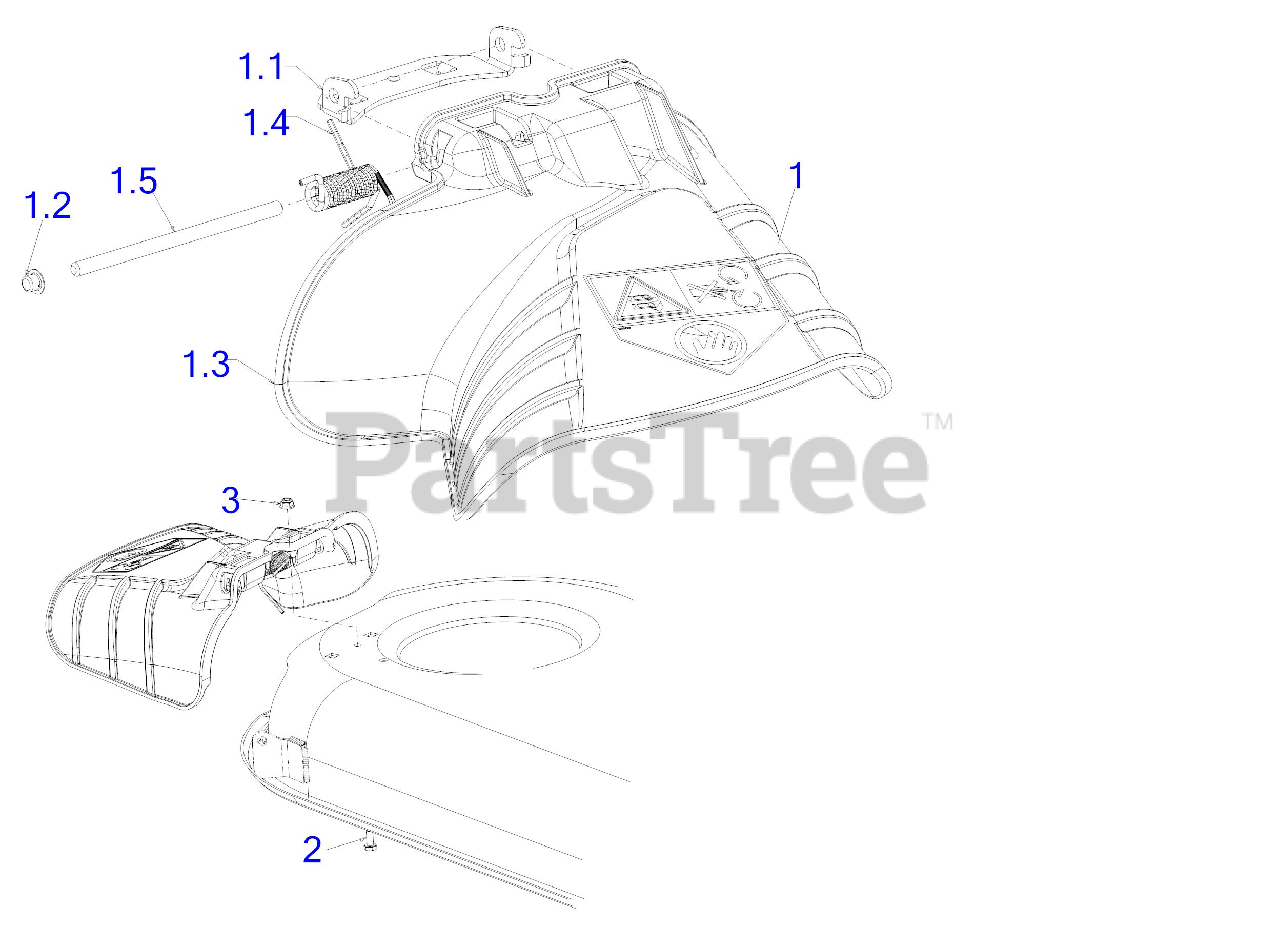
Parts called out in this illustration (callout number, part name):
1	COMPLETE CHUTE ASSEMBLY
1.1	CHUTE MOUNTING BRACKET
1.2	PUSH CAP
1.3	CHUTE
1.4	TORSION SPRING
1.5	CHUTE HINGE PIN
2	SCREW 1/4-20 x .620 GR5
3	FLANGE LOCK NUT
